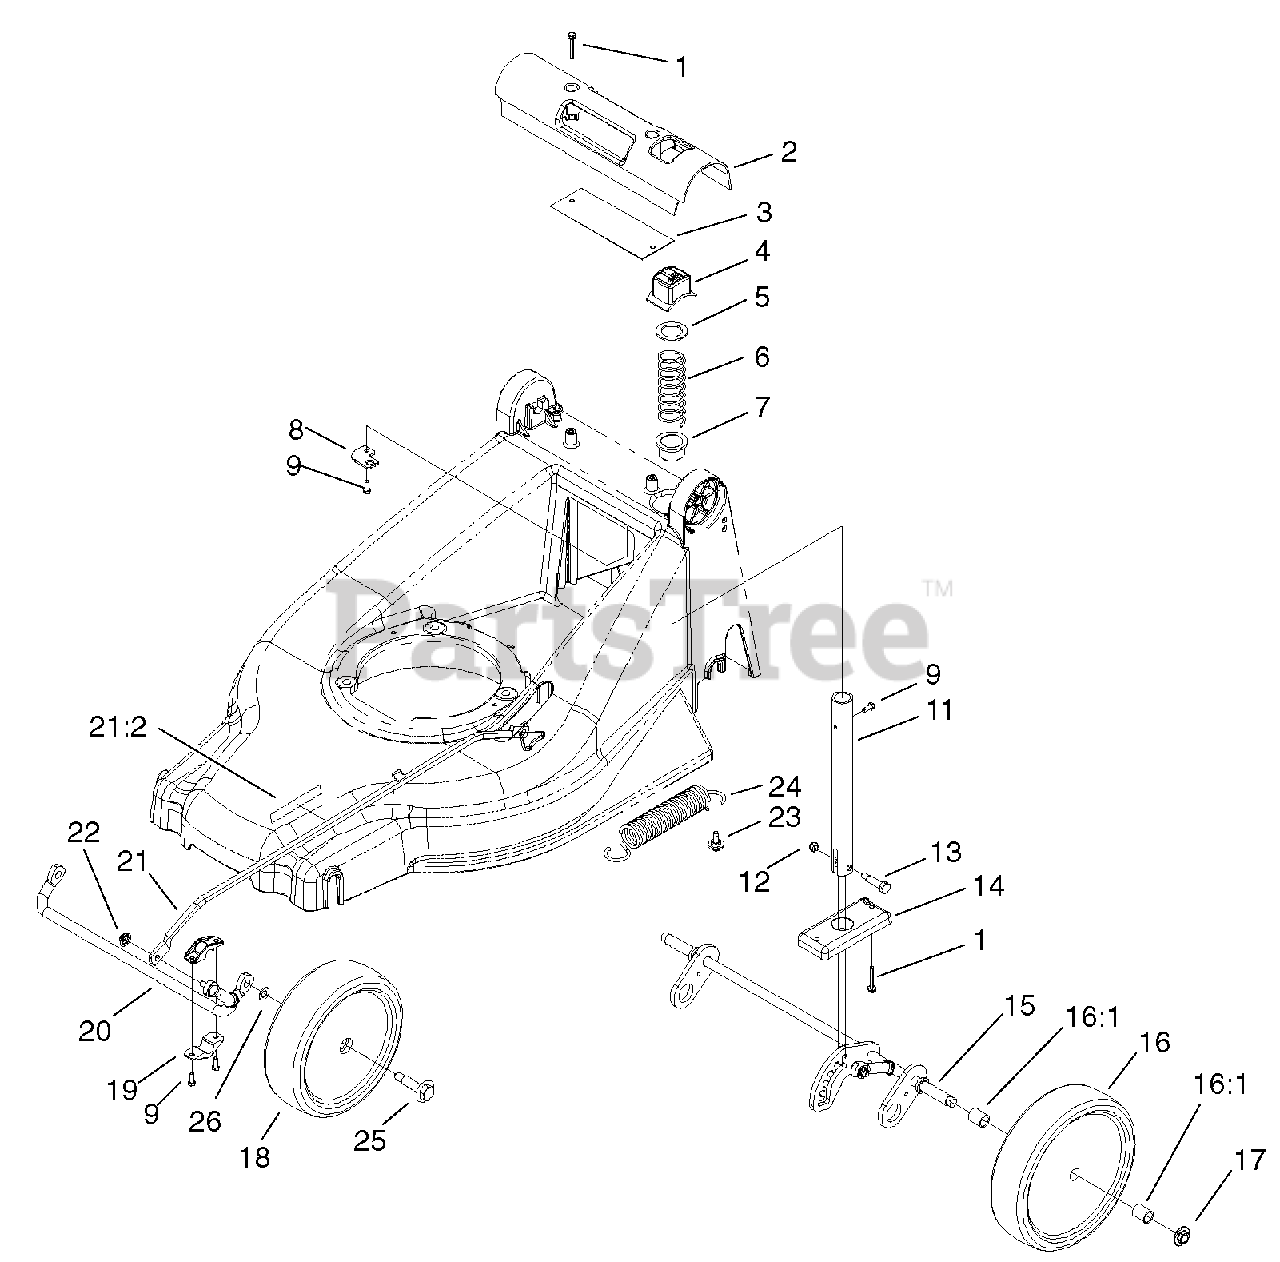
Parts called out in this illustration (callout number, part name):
1	Screw-HWH
2	Handle-Deck
3	Cover-Handle
4	Button-HOC
5	Washer-Backup
6	Spring-Compression, HOC
7	Bushing-HOC
8	Bracket-Cable, Traction (only on: 10929)
9	Screw-Taptite (only on: 10929)
9	Screw-Taptite (only on: 10924)
11	Pipe-HOC
12	Nut-Lock, NI
13	Bolt-Shoulder
14	Plate-Support, HOC
15	Rear Axle ASM
16	Wheel ASM (only on: 10929)
16	Wheel ASM (only on: 10924)
17	Nut-Lock, Flanged
18	Wheel ASM
19	Mount-Axle, Front
20	Front Axle ASM
21:2	Decal-HOC
23	Screw-Shoulder
24	Spring-Extension, HOC
25	Bolt-Shoulder
